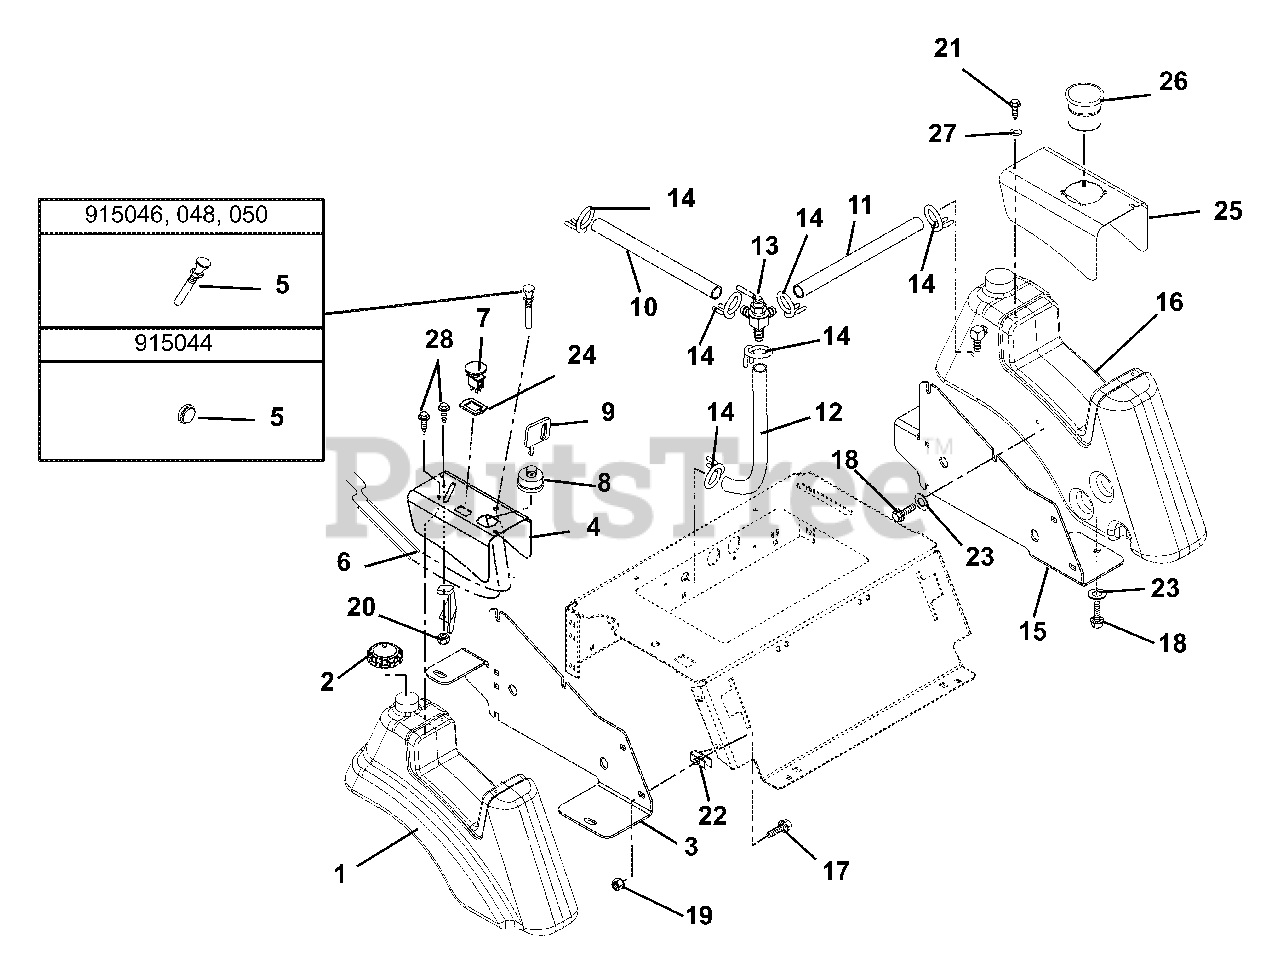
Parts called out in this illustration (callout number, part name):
1	FUEL TANK, RH
2	FUEL CAP
3	SEAT PLATE, RH
4	RH CONSOLE
5	CHOKE CABLE
6	THROTTLE CABLE
7	SWITCH, CLUTCH
8	KEY SWITCH
9	KEY -W/CAP
10	GAS LINE-BULK 1/4" I.D.
11	GAS LINE-BULK 1/4" I.D.
12	GAS LINE-BULK 1/4" I.D.
13	VALVE, FUEL
14	CLAMP-HOSE WIRE .490/.510X.116
15	SEAT PLATE, LH
16	FUEL TANK, LH
17	BLT-RDHDSQNK .38-16X1.00 G5YZ
18	BLT-SERHFWH .312-18X.75 YWZC
19	@NUT-LK-NYL-FLG .38-16 YWZC
20	NUT-LK-NYL 10-24 W/INSRT YWZC
21	SCR-MCH 10-24X3/8 SL HEX YWZC
22	RETAINER, .38 PUSH-ON
23	WSHR-FL-STL .328X1.0X.094 YWZC
24	SHIM,PTO SW (DELTA #972301)
25	LH CONSOLE
26	CUPHOLDER
27	WASHER, FENDER 3/16X3/4 YWZC
28	@SCR-MCH 10-24X.50 HWH YWZC
